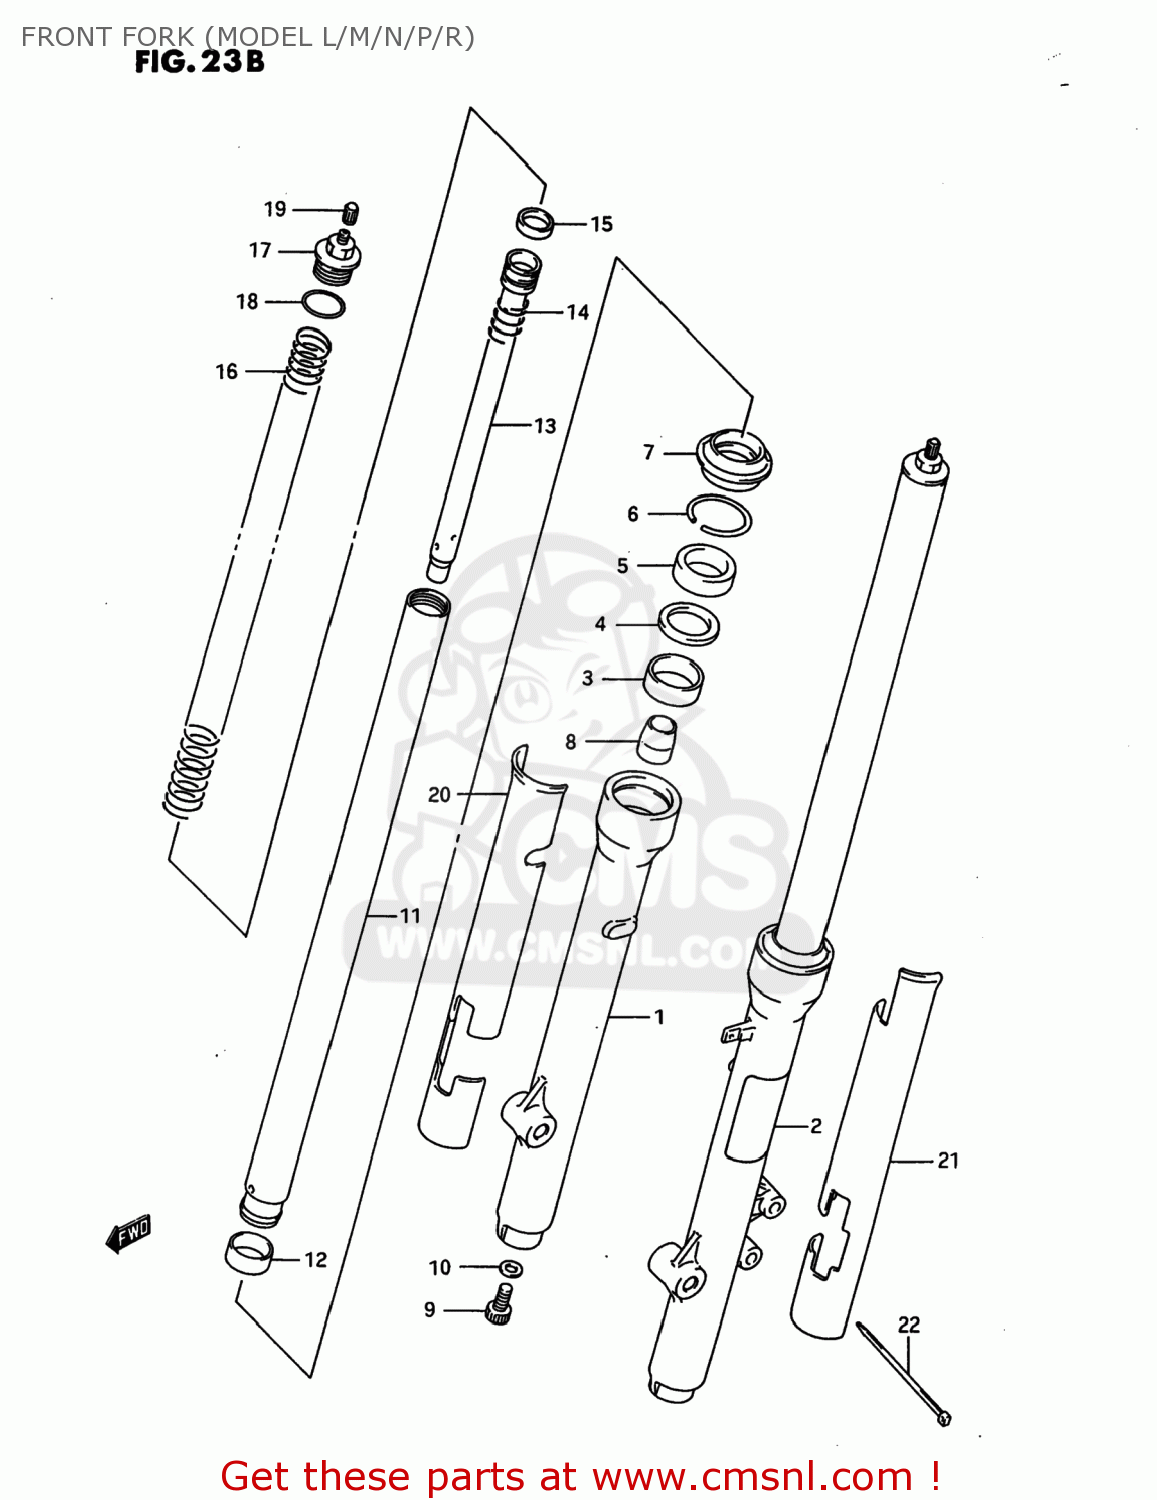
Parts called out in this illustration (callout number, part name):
1	TUBE,OUTER,RIGHT
2	TUBE,OUTER,LEFT
3	BUSH,GUIDE
4	SPACER,SEAL
5	SEAL,OIL 35X48X11
6	RING,OIL SEAL STOPPER
7	SEAL,DUST
8	PIECE,OIL LOCK
9	BOLT(8X27)
10	GASKET (NAS)
11	TUBE,INNER
12	PISTON
13	SEAT,UNDER
14	SPRING,REBOUND
15	RING,PISTON
16	SPRING,UNDER
17	BOLT,FORK INNER TUBE
18	O RING
19	CAP
20	PROTECTOR,FR FORK,R
21	PROTECTOR,FR FORK,L
22	CLAMP
